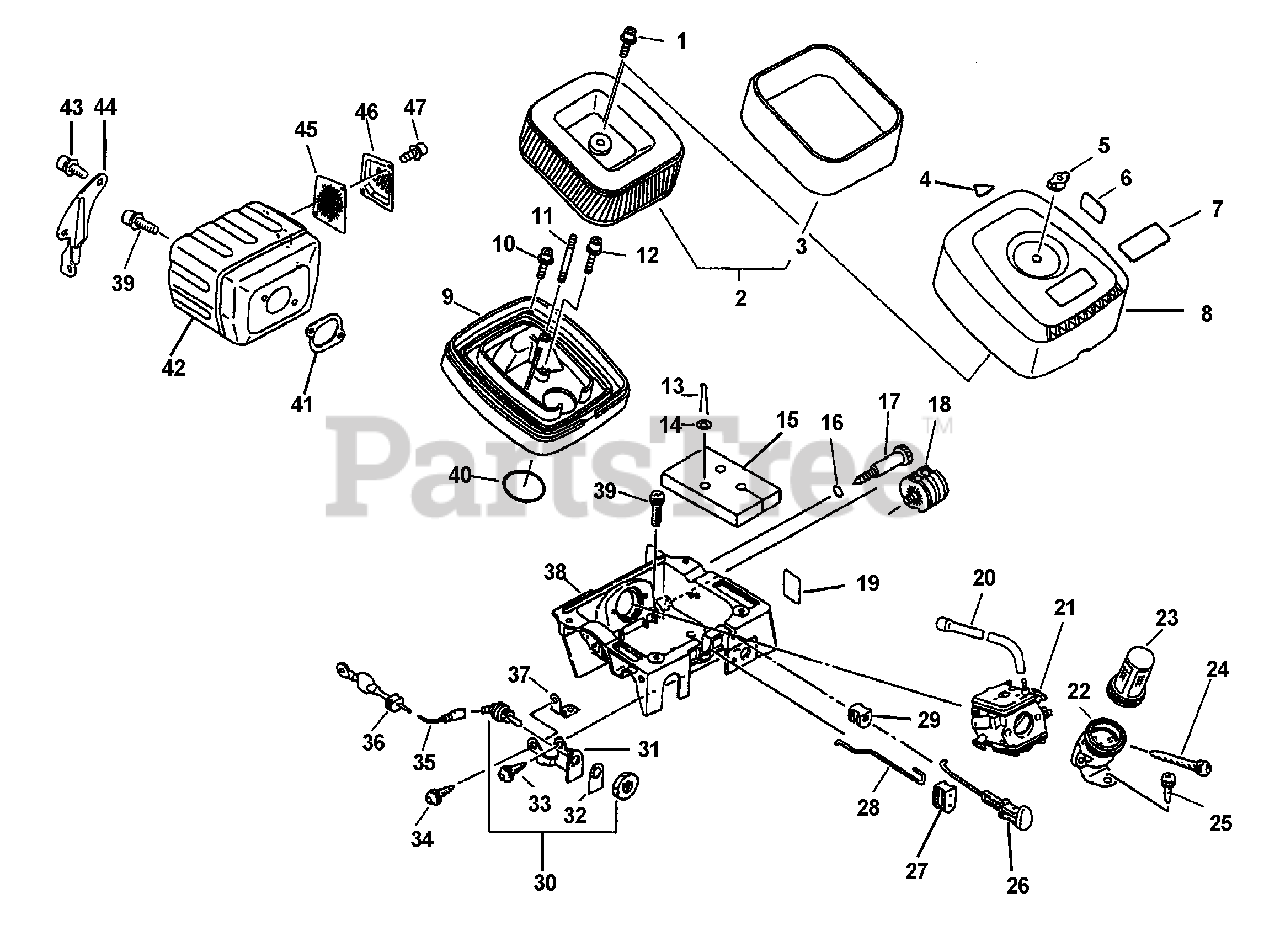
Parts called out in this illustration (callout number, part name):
1	BOLT - 5×16
2	FILTER, AIR
3	FILTER, AIR
5	NUT
6	LABEL, CAUTION
7	LABEL, MODEL
8	COVER, AIR FILTER
9	CASE, AIR FILTER
10	SCREW 5×16
12	SCREW 5×25
13	PIN, COTTER 3×18
15	PAD, FOAM
16	O-RING 7
17	SCREW, IDLE ADJUST - GRAY
19	LABEL, CAUTION - IDLE
20	PIPE, IMPULSE
21	CARBURETOR - HDA-166A
23	SCREEN, FILTER
24	SCREW 5×53
25	SCREW 5×14
26	ROD, CHOKE
27	GROMMET, THROTTLE ROD
28	ROD, THROTTLE
29	GROMMET
30	SWITCH, ON-OFF
31	BRACKET, SWITCH
32	LABEL - SWITCH
33	SCREW 5×10
34	SCREW 4×10
35	LEAD - GROUND
37	PLATE, GROUND
38	CASE, CARBURETOR
39	BOLT 5×20
40	O-RING 29
41	GASKET, EXHAUST
42	MUFFLER
43	BOLT 5×14
44	BRACKET, MUFFLER
45	SCREEN, SPARK ARRESTER
46	GUIDE, EXHAUST
47	BOLT 4×10
